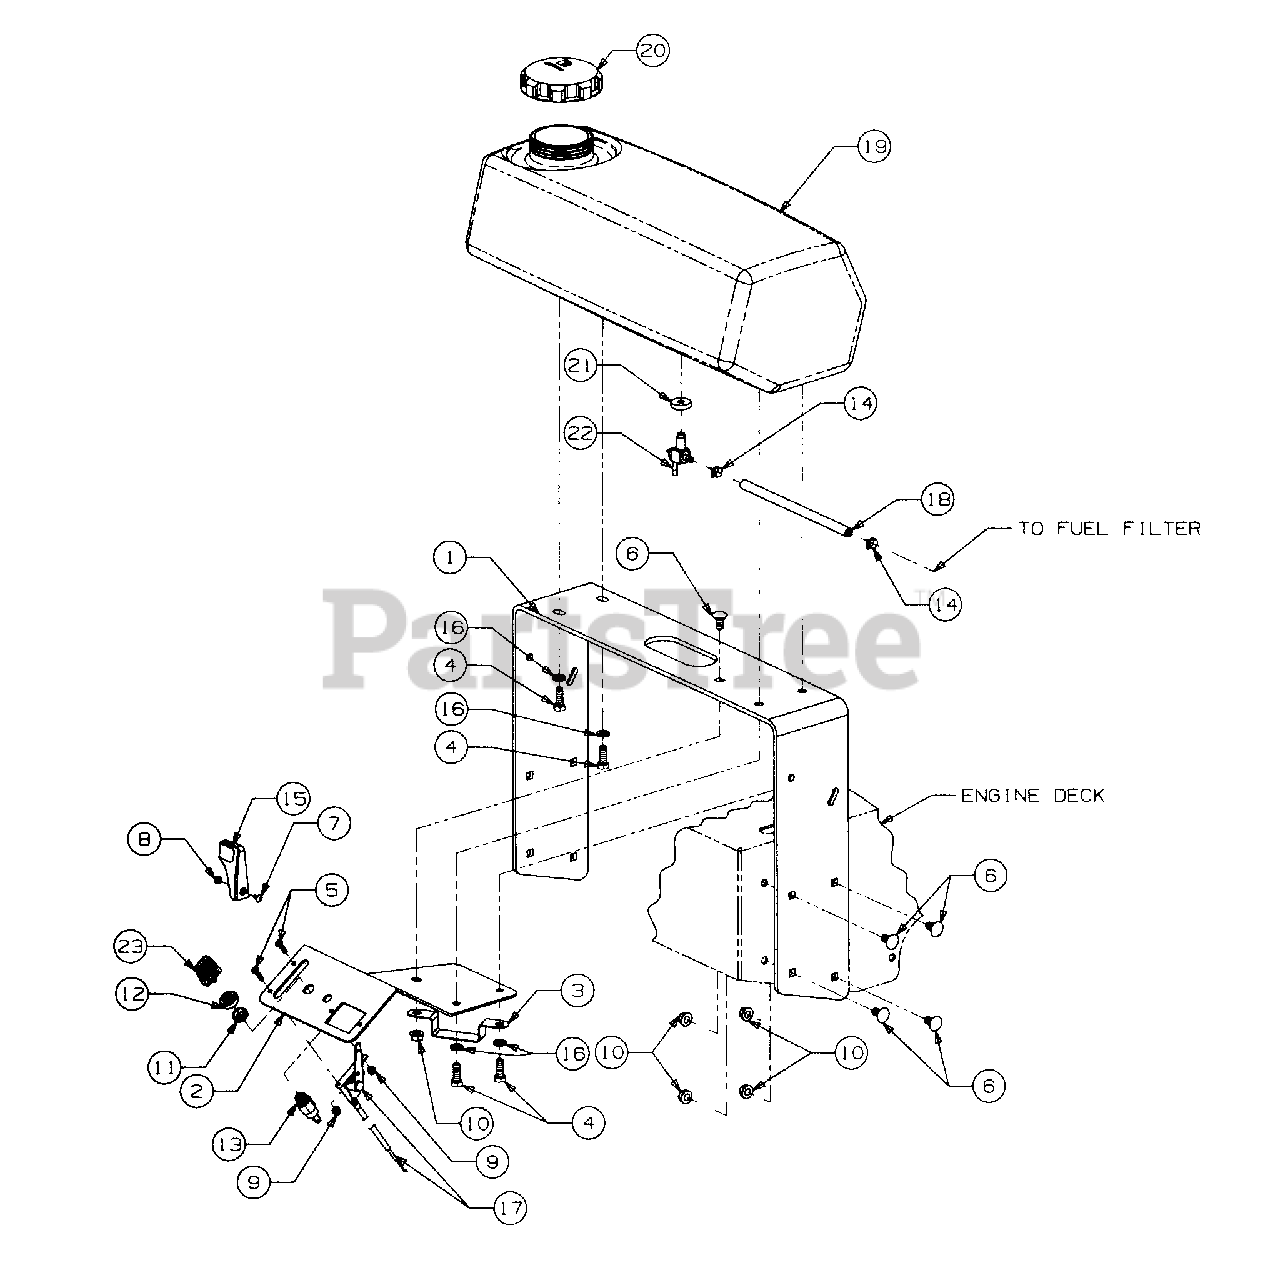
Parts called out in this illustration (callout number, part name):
1	Support, Lower Handle
2	Panel w/Graphic, Control
3	Bracket, Cable Retainer
4	Screw, Hex Cap, 3/8-16 X 1.0 Lg GR5
5	Screw, Pan Hd Cutting, #10-24 X .75 Lg
6	Bolt, Sht Nk Carriage, 3/8-16 X .75 Lg GR5
7	Screw, Cross Rec Truss Hd, #8-32 X .38 Lg
8	Nut, Hex, #8-32
9	Nut, Hex Nylock, #10-24
10	Nut, Hex Flanged Lock, 3/8-16
11	Nut, Ignition Switch, 5/8-32
12	Cap, Ignition Switch
13	Switch, Ignition
14	Clamp, Hose
15	Knob, Throttle Control
16	Washer, Lock, 3/8
17	Control, Throttle
18	Line, Fuel - 15" Lg - Order bulk fuel line Part No. 759-3330, 10 ft Lg
19	Tank w/Graphic, Fuel (lncludes Ref No. 21 & 22)
20	Cap, Fuel
21	Grommet, Shutoff Valve
22	Valve, Fuel Shutoff
23	Key, Ignition (Set of 2)
